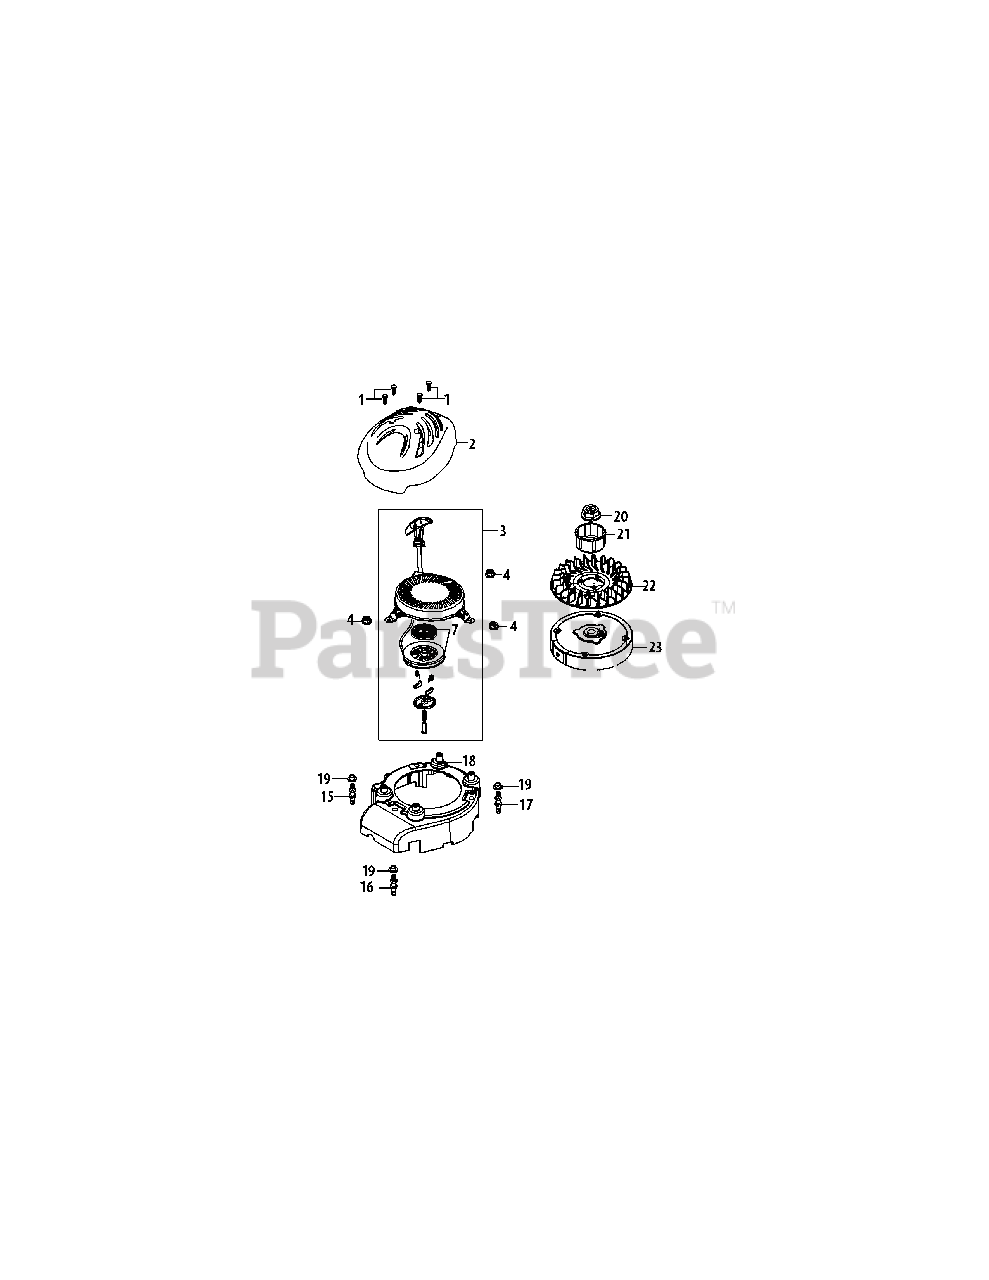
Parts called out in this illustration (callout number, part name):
1	Self-Tapping Bolt, Hilo #12-16 X 1.00"
2	See Unit Breakdown for Shroud
3	Recoil Starter Assembly
4	Nut M6 X 10 Mm
7	Recoil Pulley & Spring Assy
15	Starter/Shroud Stud Left/Black
16	Starter/Shroud Stud Front/Unmarked
17	Starter/Shroud Stud Right/White
18	Inner Shroud
19	Engine Shroud Spacer
20	Flywheel Nut M14
21	Starter Cup
22	Cooling Fan
23	Flywheel
